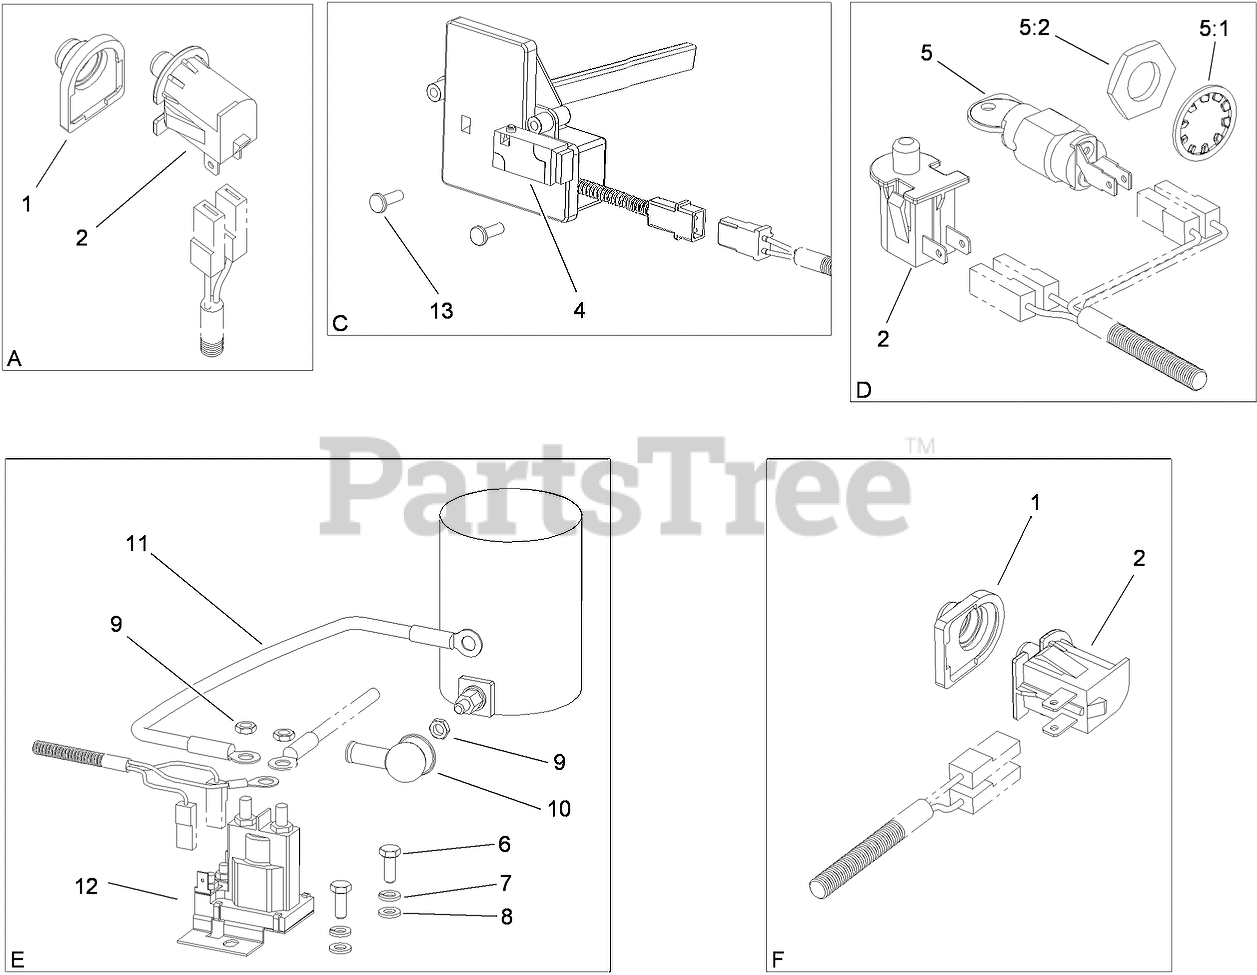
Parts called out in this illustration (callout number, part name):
1	COVER-PROTECTIVE
2	SWITCH-DELTA
4	OVERLOAD SWITCH ASM
5	STARTER SWITCH ASM
5:1	WASHER-TOOTH, INTERNAL
5:2	NUT-HH
6	SCREW-HH
7	WASHER-SPRING
8	WASHER-FLAT
9	NUT-HHF
10	BOOT-RUBBER
11	LEAD-STARTER, ELECTRIC
12	SOLENOID
13	Screw
